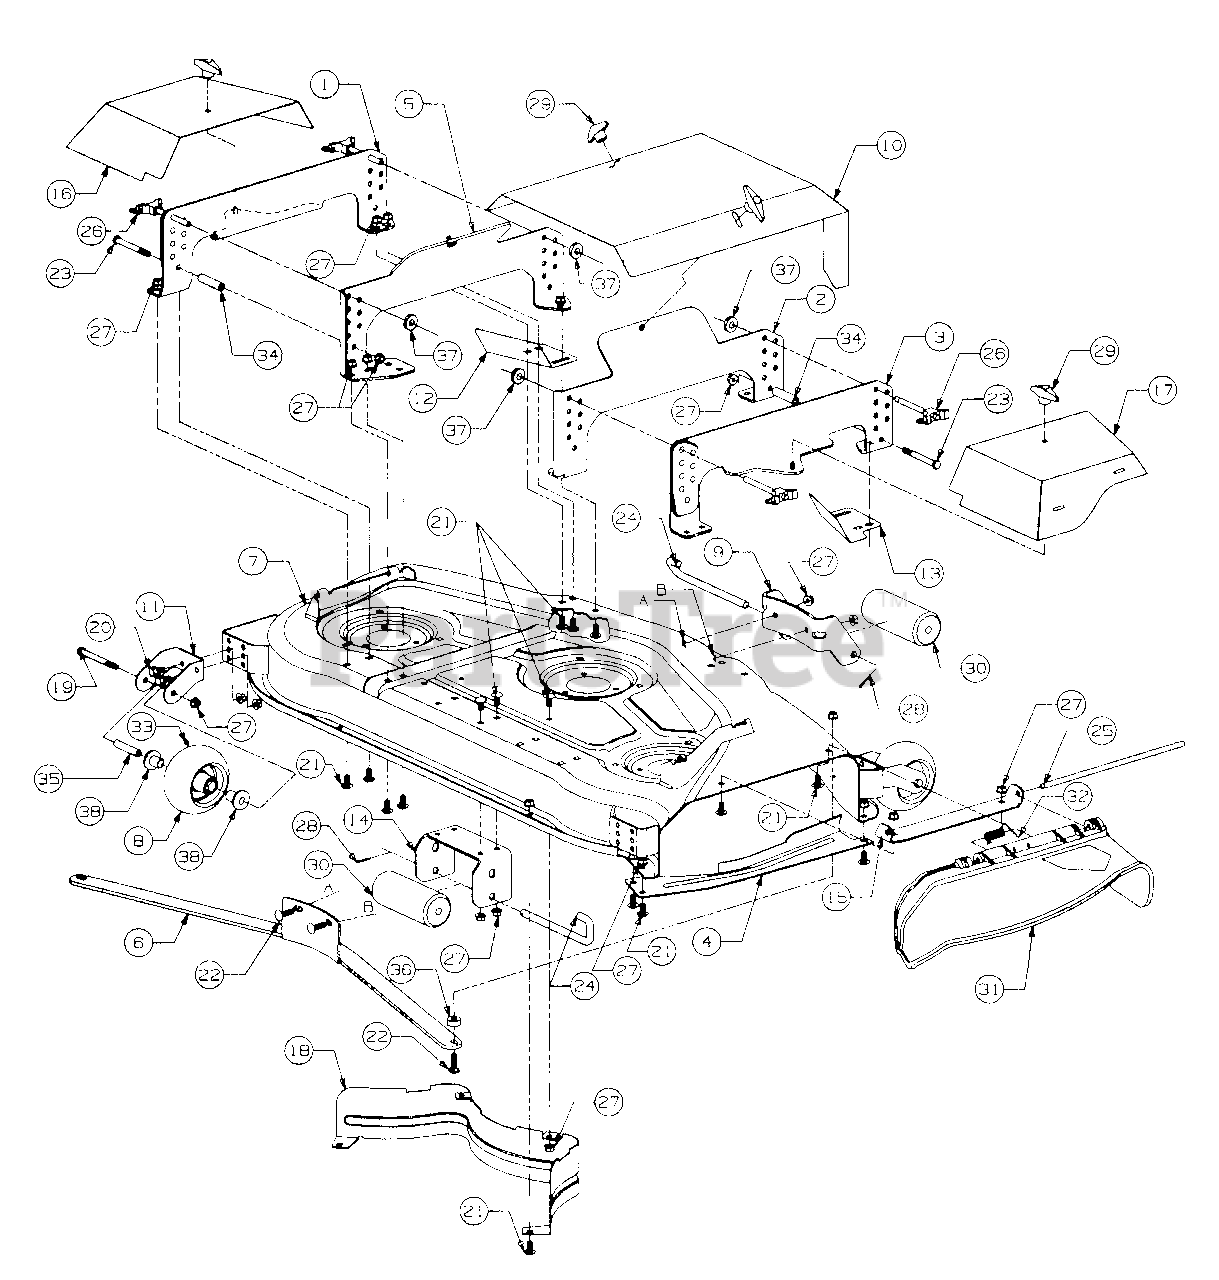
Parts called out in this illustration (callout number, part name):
5	Hanger, LH Inner
8	Wheel Assy, 5" Deck
13	Plate, RH Filler
19	Screw, Hex Cap, 3/8-16 X 4.25 Lg
20	Screw, Hex Wash Sf Tapp 3/8-16 X .88 Lg GR 5
21	Bolt, Sht Nk Carriage 3/8-16 X .75 Lg GR 5
22	Bolt, Carriage 3/8-16 X 1.25 Lg GR 5
23	Screw, Hex Cap 3/8-16 X 3.25 Lg GR 5
24	Pin, Roller, 1/2 Dia X 7.31 Lg
25	Pin, Hinge, .375 Dia X 12.55 Lg
26	Pin, Quick Release, 3/8 Dia
27	Nut, Hex Flanged Lock, 3/8-16
28	Pin, Cotter, 1/8 Dia X 1.0 Lg
29	Knob, Wing Nut
31	Deflector, Chute
32	Spring, Torsion
33	Fitting, Lube, 3/16 Drive
34	Spacer, Deck Hanger
35	Spacer, Deck Wheel
36	Spacer, Front Bar
37	Washer, Flat, .385 X .870 X .092 Thk
38	Bearing, Flange
